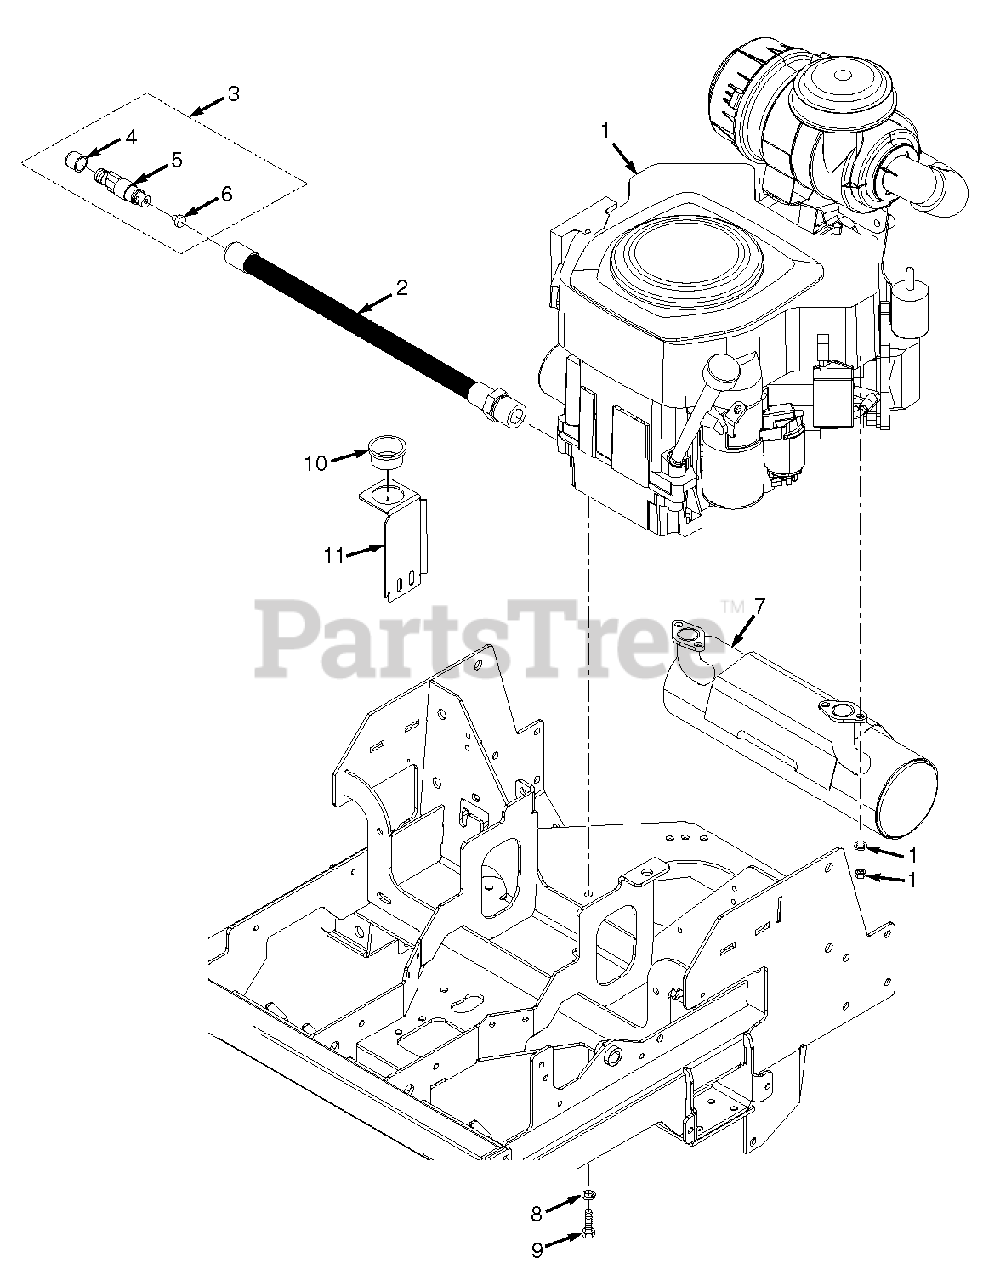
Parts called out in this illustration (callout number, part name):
1	Engine, Kawasaki 22FX (FX691V)
1	Engine, Kohler 23CV (CV730)
1	Engine, Kohler 23CV-EFI (ECV730)
1	Engine, Kawasaki 23FX (FX730V)
1	Engine, Kohler 25CV (CV740)
1	Engine, Kohler 25CV-EFI (ECV740)
1	Engine, Briggs & Stratton 26BS (44L977)
2	Hose Assembly, Engine Oil Drain - Kawasaki FS/FX
2	Hose, Oil Drain - Briggs & Stratton ELS
2	Hose, Oil Drain - Kohler CV
3	Valve Assembly, Oil Drain
5	O-Ring
7	Muffler, Kawasaki FS/FX
7	Muffler, Briggs & Stratton
7	Muffler, Kohler CV
7	Muffler, Kohler ECV (EFI)
8	Lockwasher, 3/8" Spring (Kawasaki)
9	Bolt, Hex Head 3/8-16 x 1-1/4" (Kawasaki)
9	Bolt, Hex Head 3/8-16 x 1-1/4" Self Tap (Briggs and Kohler)
9	Bolt, Hex Head 5/16-18 x 1-1/2" (Right Front Engine Mounting, Briggs and Kohler Only)
9	Nut, Serrated Flange 5/16-18 (Right Front Engine Mounting, Briggs and Kohler Only)
10	Bushing, Thick Panel Snap
11	Bracket, Oil Drain Hose
